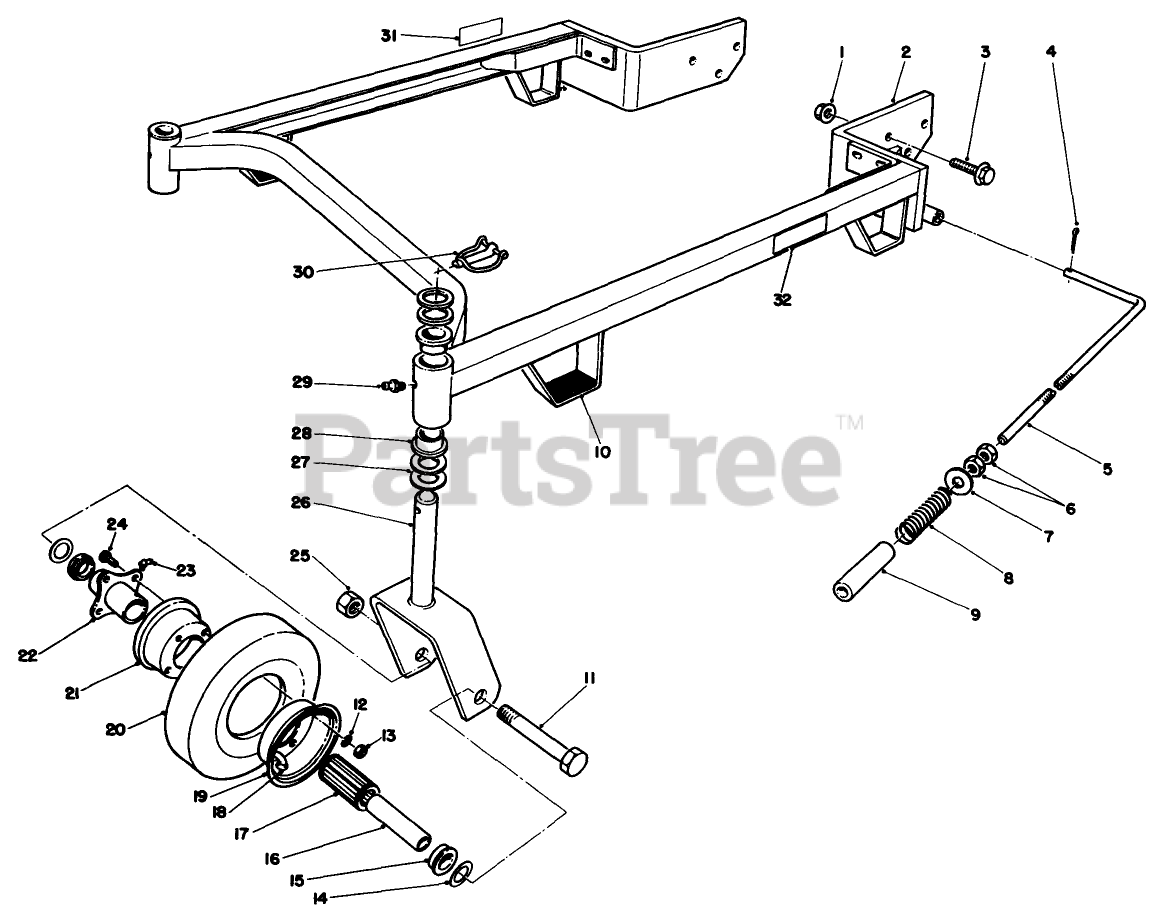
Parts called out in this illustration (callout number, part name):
1	NUT-HF
2	44" SUSPENSION WA
3	SCREW-HHF
4	PIN-COTTER
6	NUT-JAM
7	WASHER
11	SCREW-HH
12	WASHER-LOCK
13	NUT-HEX
14	WHEEL SPACER
15	RETAINER
17	ROLLER BEARING
19	WHEEL HALF-MALE
20	TIRE 8"(4-PLY)
21	WHEEL HALF-FEMALE
22	HUB - CENTERED
23	FITTING-GREASE
24	WHEEL BOLT
25	NUT-LOCK
27	WASHER-THRUST
29	FITTING-GREASE
30	PIN-LYNCH
32	DECAL-HOC, LH
